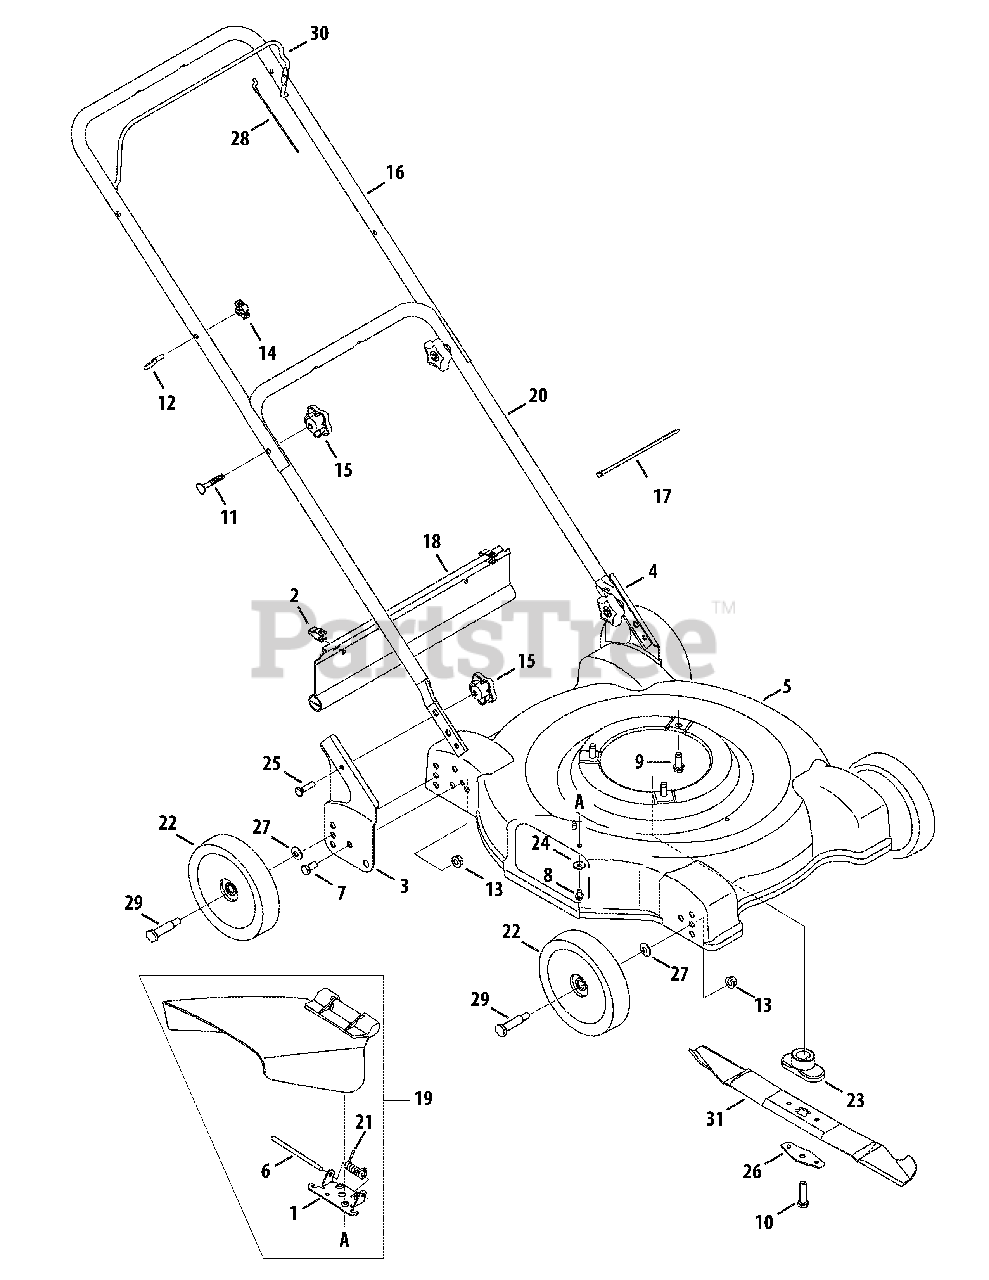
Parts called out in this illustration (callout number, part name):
1	Chute Hinge
2	Hinge Clip
3	Handle Bracket Assembly - RH
4	Handle Bracket Assembly - LH
5	Deck Assembly, 22"
6	Hinge Pin
7	Hex Cap Screw 3/8-16 x .75
8	TT Screw 1/4-20 x 0.5"
9	TT Screw 3/8-16 x 1.0
10	Hex Cap Screw 3/8-24 x 1.5
11	Carriage Bolt 5/16-18 x 2.0
12	Eye Bolt
13	Lock Nut 3/8-16
14	Wing Nut
15	Star Knob
16	Upper Handle
17	Cable Tie
18	Trail Shield
19	Hinged Chute Deflector Assembly
21	Torsion Spring
22	Wheel
23	Blade Adapter
24	Bell Washer .265 ID x .75 OD
25	Clinch Stud
26	Blade Bell Support
27	Bell Washer, .375 x .870 x .063
28	Blade Control Cable - 37.25"
29	Shoulder Screw, .498 x 1.635
30	Blade Control
31	Standard Blade, 22"
